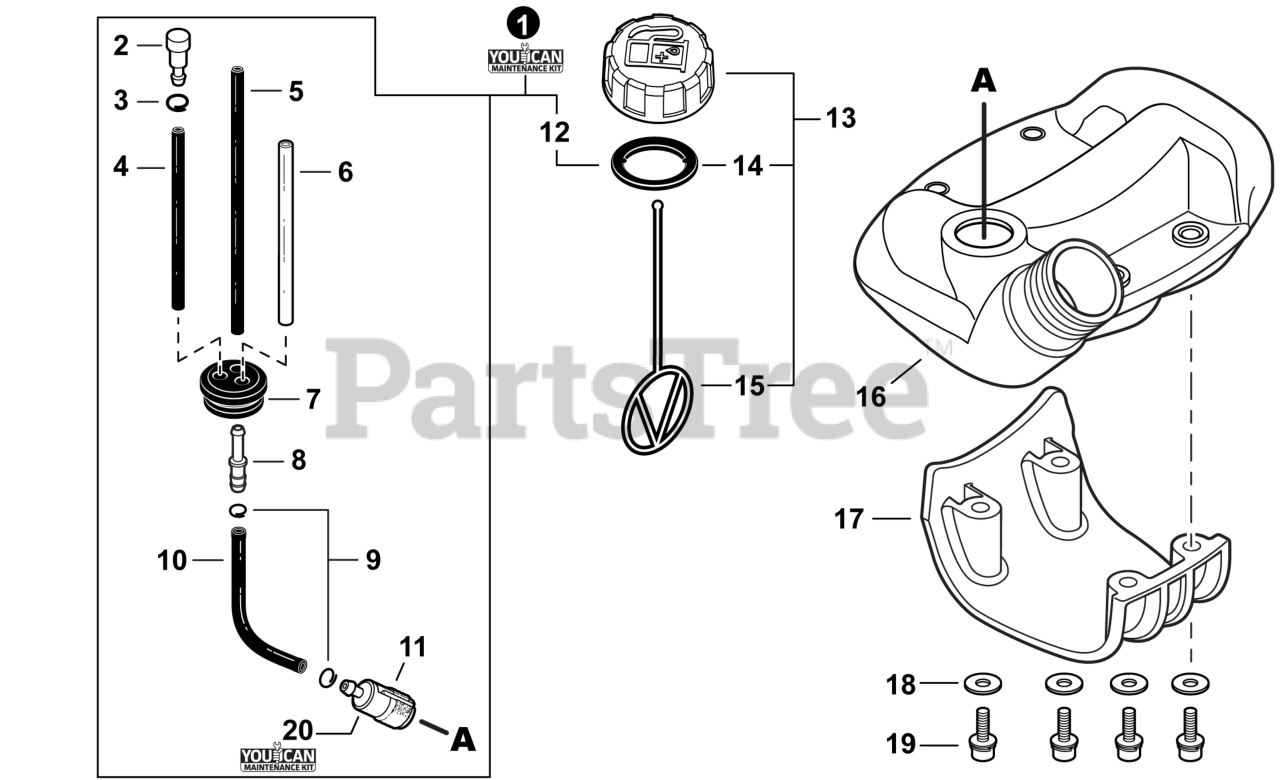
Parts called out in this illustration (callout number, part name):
1	FUEL SYSTEM KIT - YOUCANT
2	VENT ASSY
3	CLIP 6.5 MM
4	PIPE, FUEL 3x6x35 BLACK
5	PIPE, FUEL 3x5.5x67 BLACK
6	PIPE, FUEL 3x6x75 CLEAR
7	GROMMET, FUEL
8	CONNECTOR, PIPE 5x3.5
10	PIPE, FUEL - 3x5x125 - BLACK
11	FILTER, FUEL
12	GASKET, FUEL CAP
13	CAP ASSY, FUEL
14	GASKET, FUEL CAP
15	CONNECTOR, CAP L= 100 MM
16	TANK, FUEL
17	GUARD, FUEL TANK
18	WASHER 5.5x12x0.8
19	BOLT 5x25
20	TUNE-UP KIT - YOUCANT
